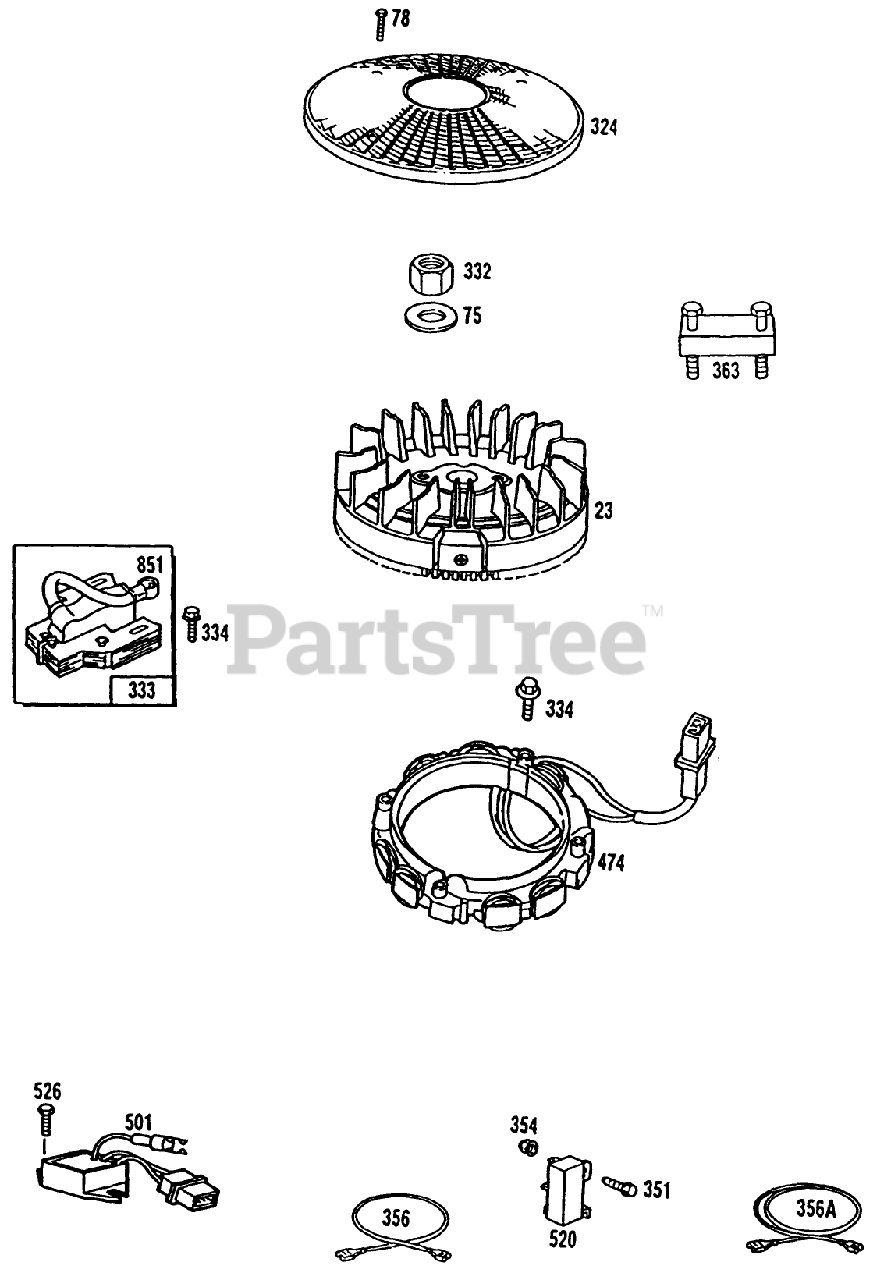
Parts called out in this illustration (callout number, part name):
75	BRIGGS-805007
78	BRIGGS-805447
324	BRIGGS-494439
332	BRIGGS-805021
333	BRIGGS-492341
334	BRIGGS-805407
351	BRIGGS 805169
354	BRIGGS-805496
356	BRIGGS-807594
356A	BRIGGS-807593
363	BRIGGS-19203
520	BRIGGS 807527
526	BRIGGS-805448
851	BRIGGS-221798
